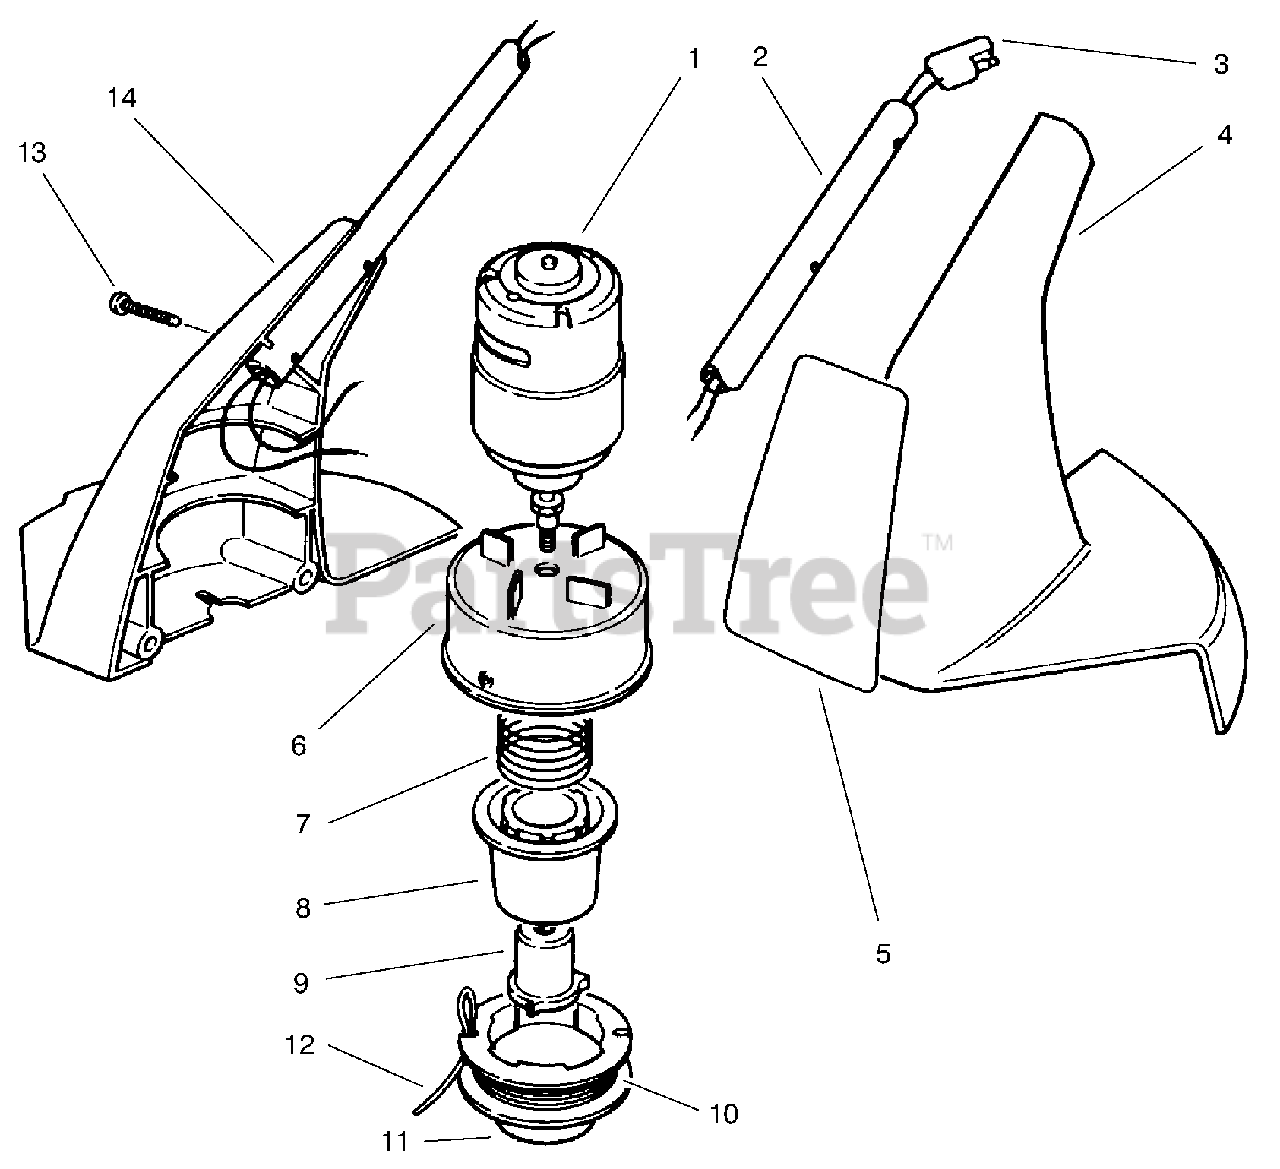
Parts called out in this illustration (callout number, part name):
2	Extension-Handle
3	Wiring Harness-Lower
4	Housing-Motor L.H.
5	Decal-7"
6	Drum w/Eyelet
10	Line, Cutting Package of 12' by .050 Dia. Prewound Spool (Whole Goods)
12	Line, Cutting Package of 30' by .050 Dia. Line in Coil (Whole Goods)
14	Housing-Motor R.H.
